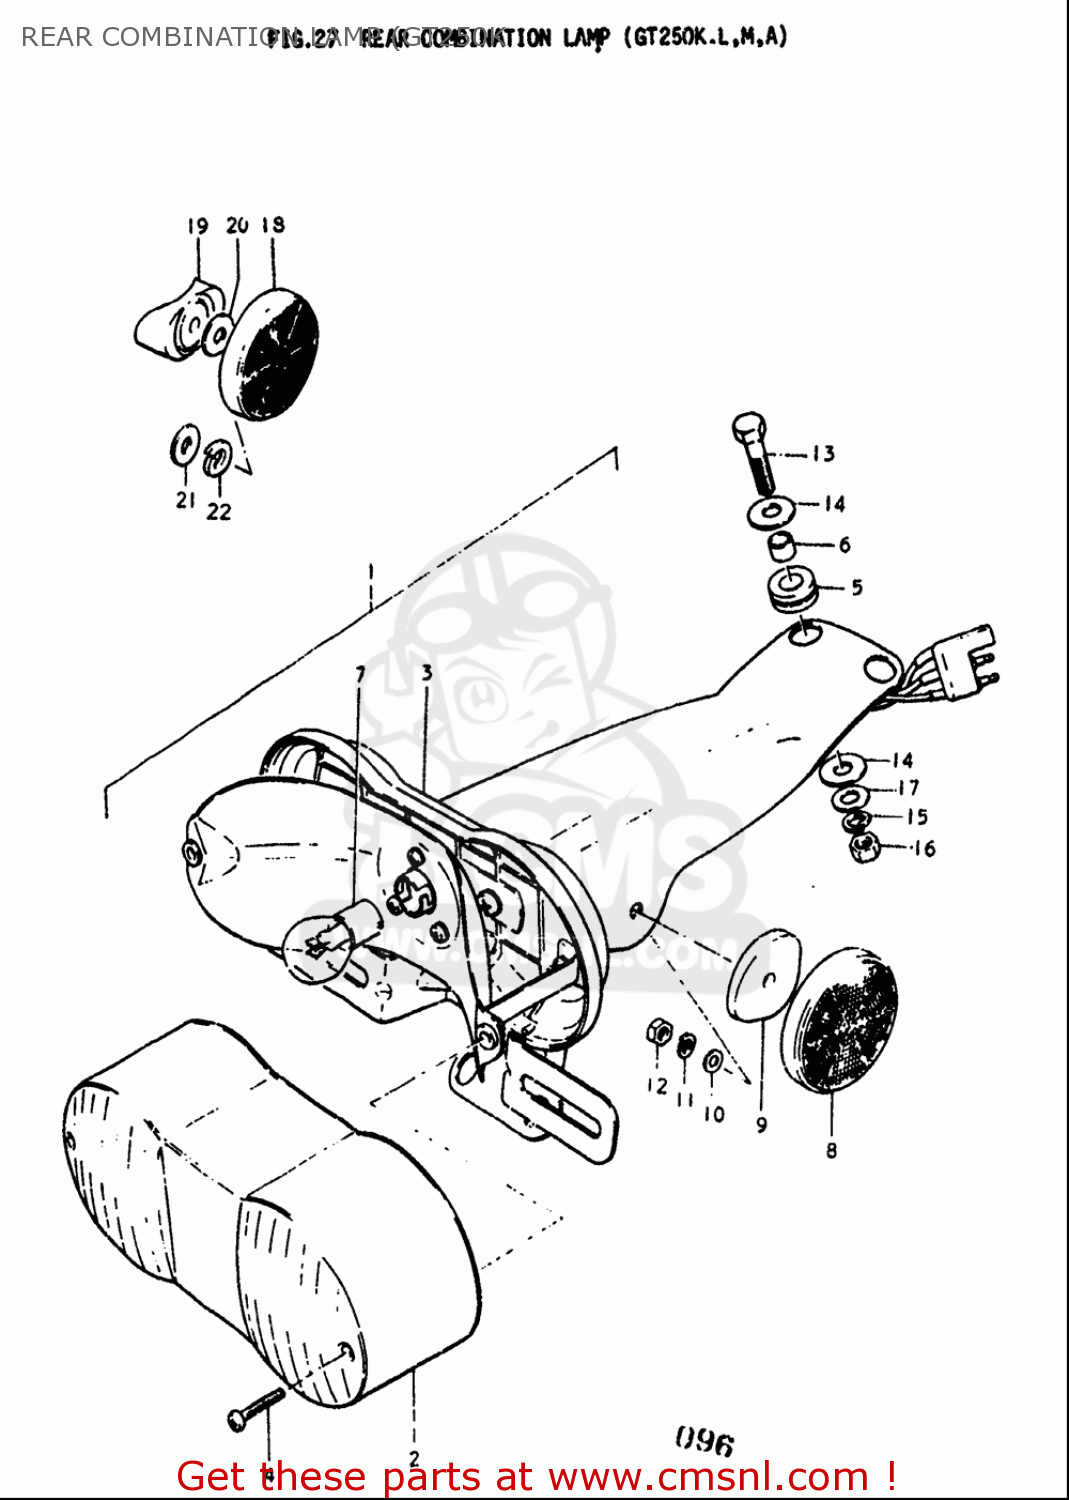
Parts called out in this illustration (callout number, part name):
2	LENS,RR COMBINATION LAMP
3	HOUSING,RR COMBINATION LAMP
5	CUSHION
6	SPACER
7	BULB(12V23W)
10	WASHER(5.5X18X1)
11	WASHER,LOCK
12	NUT
13	BOLT
14	WASHER(6.5X20X1.6)
15	WASHER,LOCK
16	NUT
17	WASHER
18	REFLEX REFLECTOR,RR
19	SPACER
20	WASHER(6.5X20X1.6)
21	WASHER
22	WASHER,LOCK
